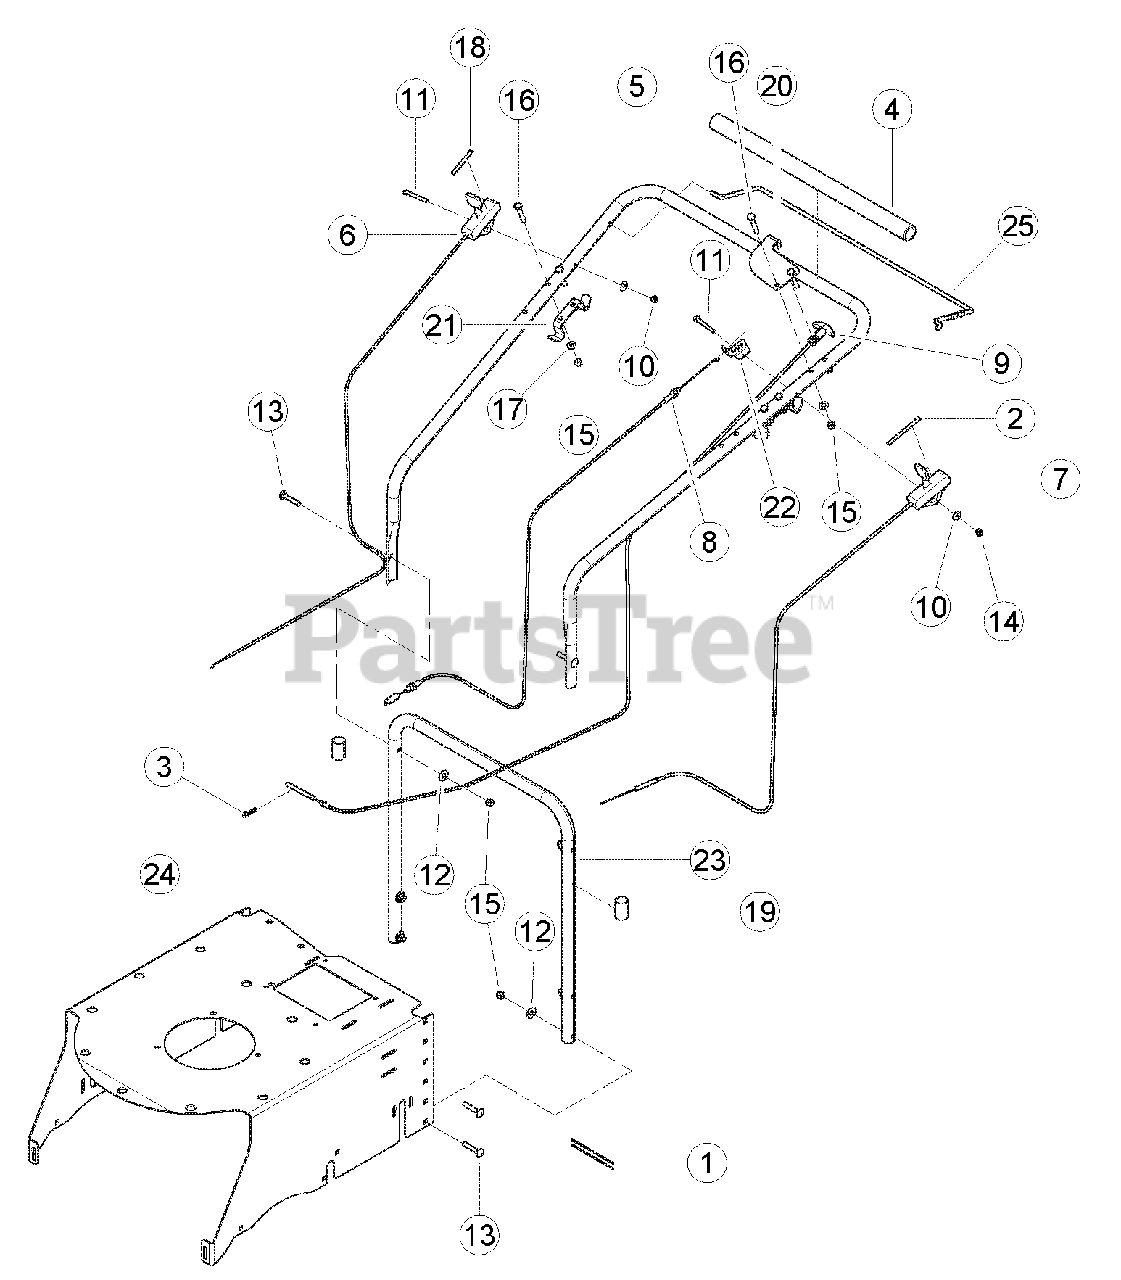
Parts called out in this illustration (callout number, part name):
1	STRAP, NYLON TIE
2	DECAL, 3 SPEED
3	CLIP, HAIRPIN ZP
4	PAD, FOAM HANDLEBAR
5	HANDLEBAR, BEARVAC UPPER
6	CONTROL, THROTTLE
7	CONTROL, TRANS. SHIFT
8	CONTROL, CLUTCH ENGAGEMENT
9	CONTROL, HEIGHT ADJUSTMENT
10	WASHER, 1/4 FLAT
11	BOLT, 1/4 X 2 HEX HD
12	WASHER, 5/16 FLAT
13	BOLT, 5/16 X 1-3/4 CRG GR5 ZP
14	NUT, 1/4 NYLOCK
15	NUT, 5/16 NYLOCK
16	BOLT, 5/16 X 1-3/4 HEX HD
17	WASHER, 5/16 SAE FLAT
18	DECAL, THROTTLE CONTROL
19	CAP, PLASTIC 7/8 IN
20	BRACKET, BEARVAC CABLE MOUNT
21	BRACKET, BAG HANGER
22	BRACKET, CLUTCH CABLE
23	HANDLEBAR, BEARVAC LOWER
24	SUPPORT, BEARVAC FRAME
25	BAIL, BEARVAC CLUTCH CONTROL
